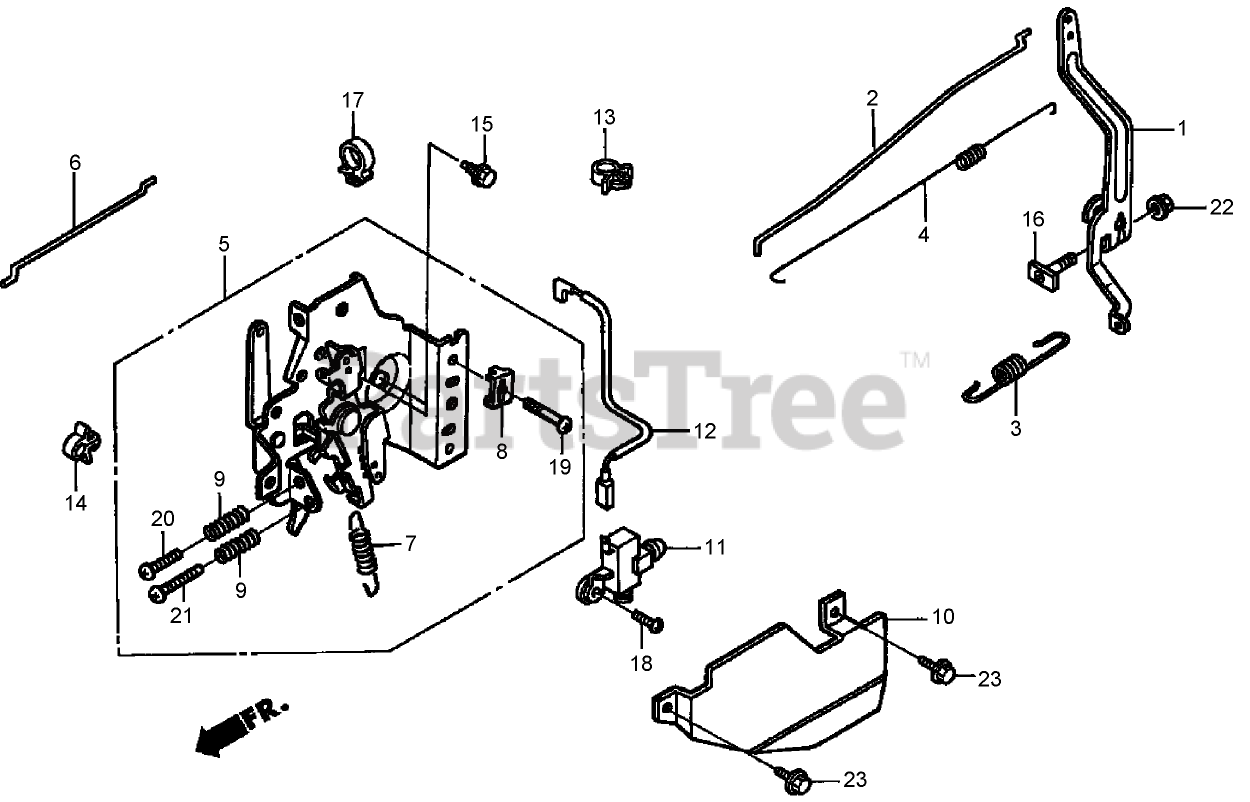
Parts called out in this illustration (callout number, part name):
1	Arm-Governor
2	Rod-Governor
3	Spring-Governor (STD)
4	SPRING-RETURN, THROTTLE
5	CONTROL ASM
6	Rod-Choke
7	Spring-Lever
8	Holder-Cable
9	SPRING-ADJUSTING, CONTROL
10	Protector-Control
11	ENGINE STOP SWITCH ASM
12	WIRE-SWITCH, STOP
13	CLAMP-PIPE, BRAKE
14	HOLDER-WIRE, STOP SWITCH
15	BOLT-FLANGE (6X12) (C T200)
16	BOLT-ARM, GOVERNOR
17	CLIP-HARNESS, WIRE
18	Screw-Pan (4X8)
19	Screw-Pan (5X16)
20	Screw-Pan (5X20)
21	Screw-Pan (5X28)
22	NUT-FLANGE (6 mm)
23	Bolt-Flange (6X10)
